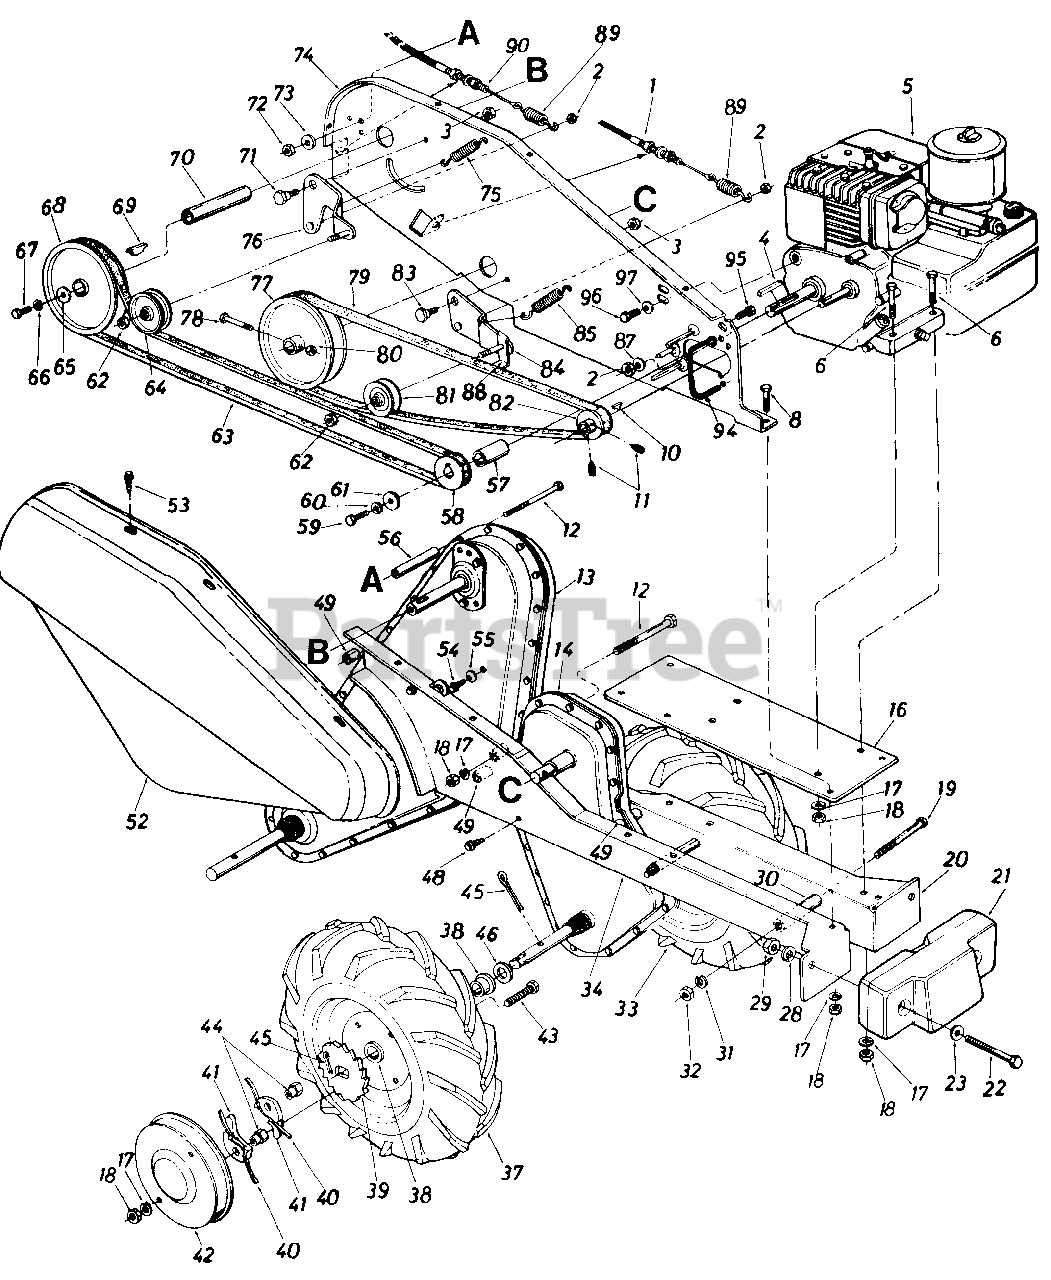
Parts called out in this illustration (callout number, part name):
1	Clutch Control Cable
2	Hex Cent. L-Nut 1/4-20 Thd.
3	Hex Cent. L-Nut 3/8-16 Thd.
4	Sq. Key 3/16" Dia. x .75
5	Engine
6	Hex Bolt 5/16-18 x 1.50" Lg.
8	Hex Bolt 5/16-18 x .75" Lg.
10	Hi-Pro Key #5 Woodruff
11	Set Scr. 1/4-28 x .25" Lg.
12	Hex Bolt 5/16-18 x 3.0" Lg.
18	Hex Nut 5/16-18 Thd.
19	Hex Bolt 3/8-24 x 3.0" Lg.
22	Hex Bolt 1/2-13 x 4.0" Lg.*
23	Fl-Wash. 1/2" I.D. x 1.0" O.D.
28	L-Wash. 1/2" I.D.
29	Hex Nut 1/2-13 Thd.*
30	Spacer 3/8" I.D. x 5/8" O.D. x 2.18" Lg.
31	L-Wash. 3/8" I.D.
32	Hex Nut 3/8-24 Thd.*
33	Comp. Wheel Ass'y.-L.H.
38	Flange Brg. 7/8" I.D. x 1.12" Lg.
39	Ratchet Wheel
40	Nylon Spring
41	Pawl .44" I.D.
42	Wheel Cover
43	Hex Bolt 5/16-18 x 1.25" Lg.*
44	Special Hex Nut 5/16-24 Thd.
45	Cotter Pin 1/8" Dia. x 1.25"-Lg.*
46	Fl-Wash. 7/8" I.D. x 1-3/8" O.D. x .06
48	Hex Wash. Self-Tap Scr. 5/16-24 x .50" Lg.
49	Spacer 5/16" I.D. x 16 Ga. x.96" Lg.
52	Belt Cover
53	Hex Wash. S-Tap Scr. 1/4-20 x.50" Lg.
54	Hex Wash. S-Tap Scr. 1/4-20- 0 x 3/8" Lg.
55	Bell-Wash. 1/4" I.D.
56	Spacer 3/8" I.D. x 1/2" O.D. x2.0" Lg.
57	Spacer 3/4" I.D. x 1.12" O.D. x 1.56" Lg.
58	1/2" "V"-4L Pulley 3/4" I.D. x 2.59" O.D.
59	Hex Bolt 3/8-24 x 1.00" Lg.
60	L-Wash. 3/8" I.D.*
61	Fl-Wash. 3/8" I.D. x 1.25" O.D.
62	Hex L-Nut 3/8-24 Thd.
63	"V"-Belt 1/2" X 54" Lg.
64	Fl-Idler Pulley 3.75" O.D. x 3/8" I.D.
65	Fl-Wash. .25" I.D. x .93" O.D. x .1 20
66	L-Wash. 1/4" I.D.
67	Hex Bolt 1/4-28 x .75" Lg.
68	Split Pulley 6" Dia. x 5/8" I.D.
69	Hi-Pro Key
71	Shld. Bolt 1/2" Dia. x .210" Lg.
72	Hex Nut 5/16-18 Thd.
73	L-Wash. 5/16" I.D.
74	Side Plate Ass'y.
75	Ext. Spring .50" O.D. x 1.55"-Lg.
76	Idler Bracket Ass'y.-Tines
77	Pulley 6" Dia. x 5/8" I.D.
78	Hex Bolt 1/4-28 x 1.50" Lg.
79	'V"-Belt 1/2" X 42" Lg.
80	Hex Cent. L-Nut 1/4-28 Thd.
81	"V"-Idler Pulley 2-5/8" O.D.
82	1/2" "V"-Pulley 2-1/4" O.D. x .50" I.D.
83	Shld. Bolt 1/2" Dia. x .160" Lg.
84	Idler Bracket Ass'y-Wheels
85	Ext. Spring .50" O.D. x 1.97"-Lg.
87	Bell-Wash. 1/4" I.D.
88	Belt Keeper Ass'y.
90	Clutch Control Cable
94	Belt Keeper
95	Hex Bolt 1/4-20 x 1.25" Lg.
96	Hex Bolt 5/16-24 x .62" Lg.
97	Bell-Wash. 5/16" I.D.
